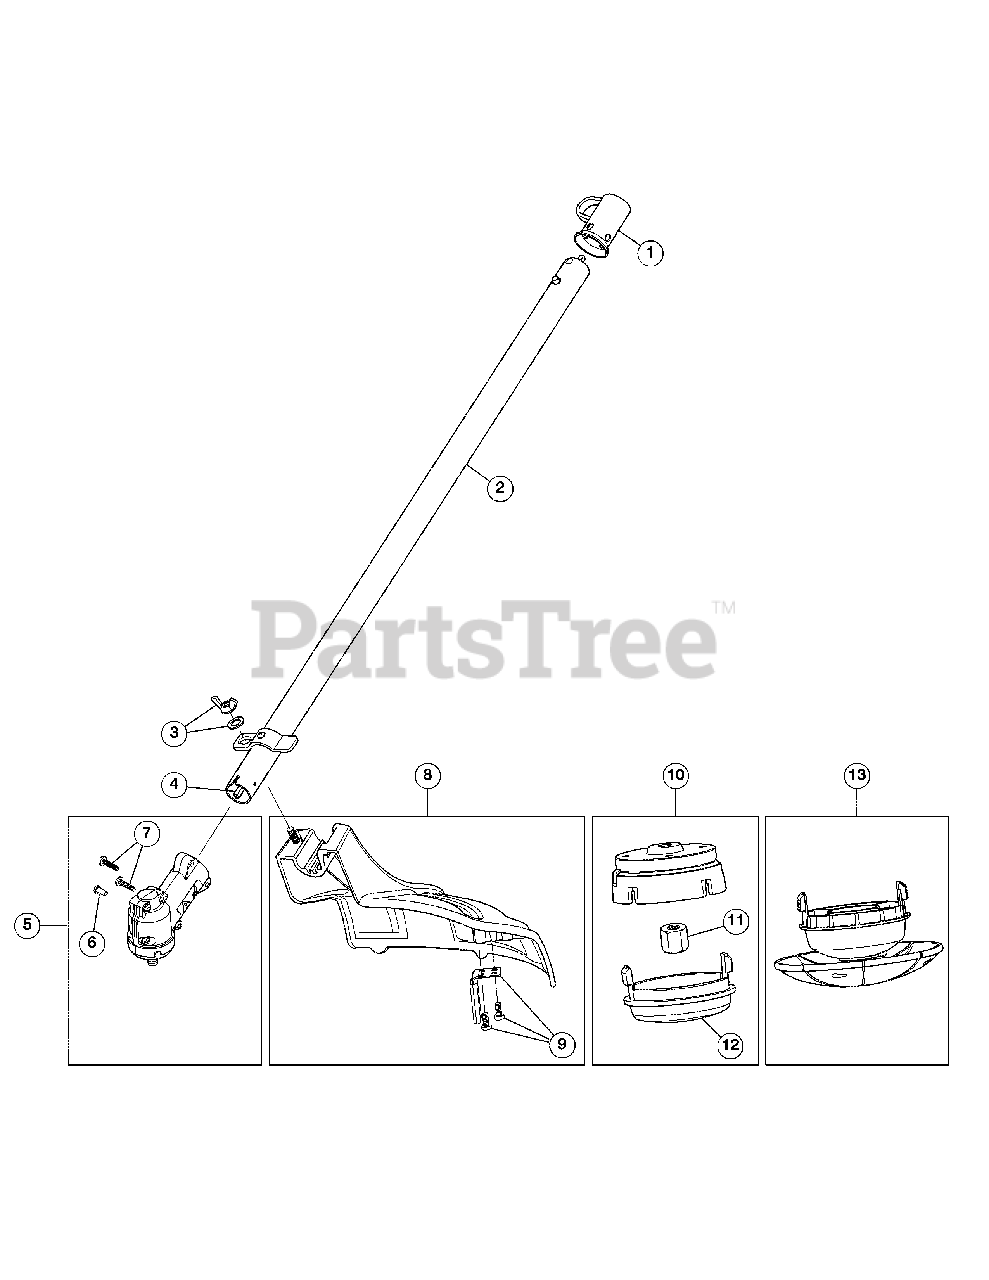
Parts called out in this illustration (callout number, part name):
1	Hanger
2	Lower Shaft Housing Assembly
3	Shield Mounting Hardware
4	Lower Flexible Drive Shaft
5	Gearbox Assembly (Incl. 6 & 7)
6	Gearbox Anti-Rotation Screw
7	Gearbox Mounting Hardware
8	Shield Assembly (Incl. 9)
9	Blade Assembly
10	Aero-Flex Cutting Head (Incl. 11 & 12)
12	Aero-Flex Cap
13	Aero-Flex Glider
